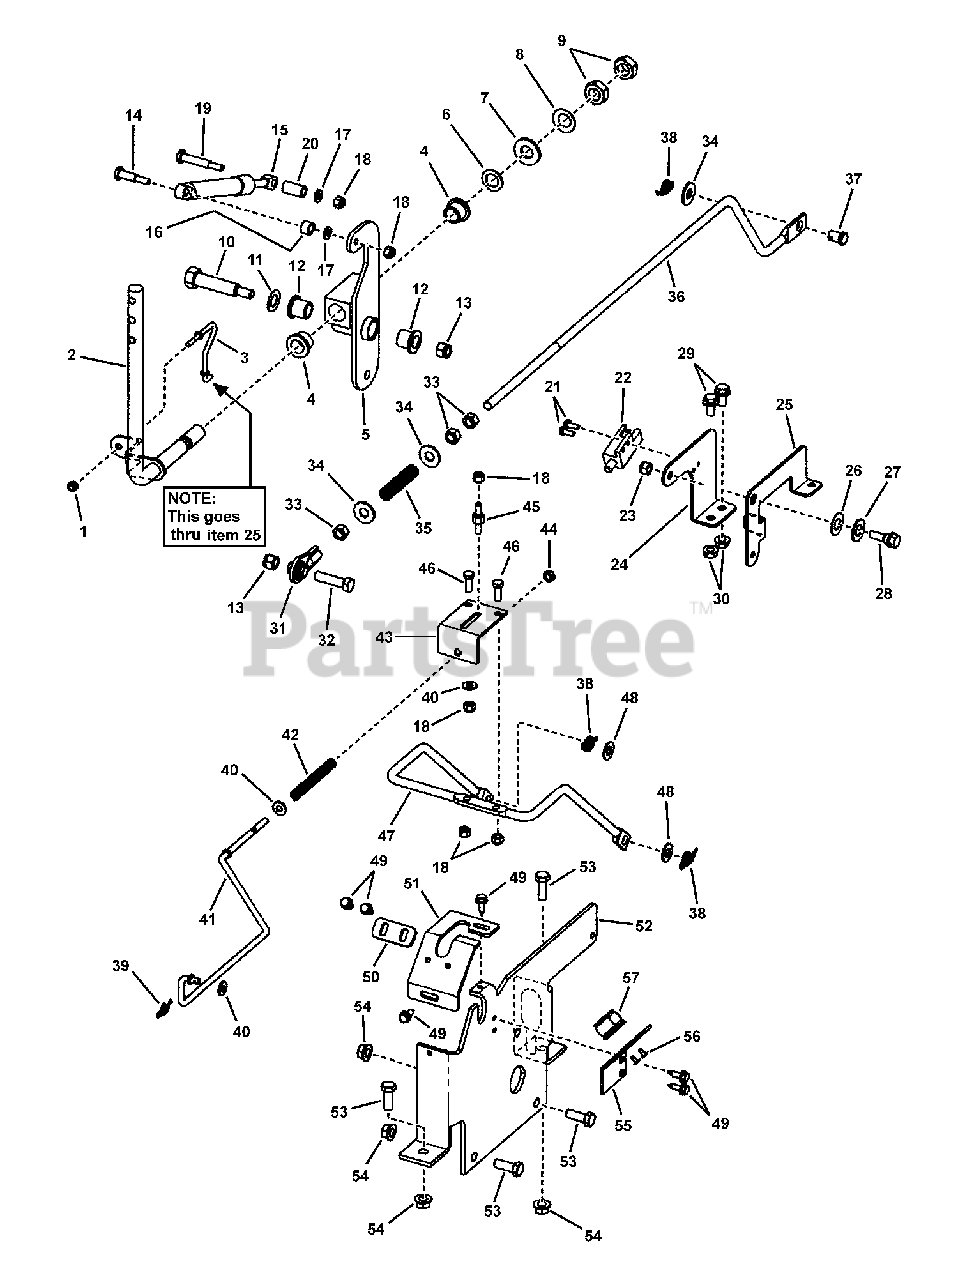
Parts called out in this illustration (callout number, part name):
1	NUT, Hex Lock Nylon, #10C YZ
2	* WELD, Control Arm, LH, Yellow
3	* HOOK, Park Brake
4	* BUSHING, ST, Powdered Metal
5	* WELD, Control Bracket, LH, Yellow
6	* WASHER, Nylon, 5/8 ID.X1"OD.X.065
7	* WASHER, .668X1.324X.098 YZ
8	* WASHER, Bellville, .64X1.125X.028
9	* NUT, Hex, Jam, 5/8F ZP
10	* SHOULDER BOLT, 3/8C
11	* WASHER, Thrust, .562 X 1.000 X .031
12	* BEARING, Flange, 9/16
13	* NUT, Hex, 3/8C, Nylock YZ
14	* SHOULDER BOLT, 5/16 X 1/4C
15	* DAMPENER
16	* SPACER, .33 X .50 X .355, Yellow
17	* WASHER, 1/4" ID, Harden
18	NUT, Hex Lock Nylon, 1/4C YZ
19	* SHOULDER BOLT, 5/16 X 1/4C
20	* SPACER, .33 X .50 X .929, Yellow
21	CAPSCREW, Hex Head Flange Taptite, TORX, #10C X1/2 YZ
22	SWITCH, DPDT
23	NUT, Hex, Lock, 5/16C ESNA YZ
24	BRACKET, Park Brake, Lower, LH, Yellow
25	BRACKET, Park Brake, Lower, RH, Yellow
26	WASHER, 1/2 x .090 Flat
27	WASHER, .531X1X.063 BZ
28	BOLT, Shoulder, 5/16C X.704,.435 DIA,YZ
29	CAPSCREW, Hex Head, Whiz Lock, Flange, 5/16C X5/8 GR5 YZ
30	NUT, Hex Flange Lock, 5/16C GR5 YZ
32	* CAPSCREW, Hex Head, 3/8C X1-1/2 GR5 YZ
33	* NUT, Hex, 3/8F GR5 YZ
34	WASHER, .438X1X.084 YZ
35	* SPRING, Brake Compression
36	* ROD, Link Fwd/Rev
37	* CLEVIS PIN, 7/16 X 1
38	PIN, Cotter, 1/2 Self, YZ
39	PIN, Cotter
40	WASHER, .28X.63X.065 YZ
41	ROD, Park Brake
42	SPRING, Compression
43	BRACKET, Park Brake
44	NUT, Hex, Lock, Taptite, 1/4C GR.B YZ
45	ROD, Hanger
46	CAPSCREW, Hex Head, 1/4C X3/4 GR5 YZ
47	ROD, Park Brake
48	WASHER, 3/8 SAE YZ
49	* CAPSCREW, Hex Head Flange Taptite, 1/4C X3/4 BZ
50	* PLATE, Fwd/Rev Adjust
51	* TRACK, Control STICK, RH
52	* BRACKET, Control, LH
53	* CAPSCREW, Hex Head, 3/8C X1 GR5 YZ
54	* NUT, Hex Flange Lock, 3/8C YZ
55	* BRACKET, Rod Holder, RZT
56	* POP RIVET, 1/8X3/8
57	* CLIP, Spring
